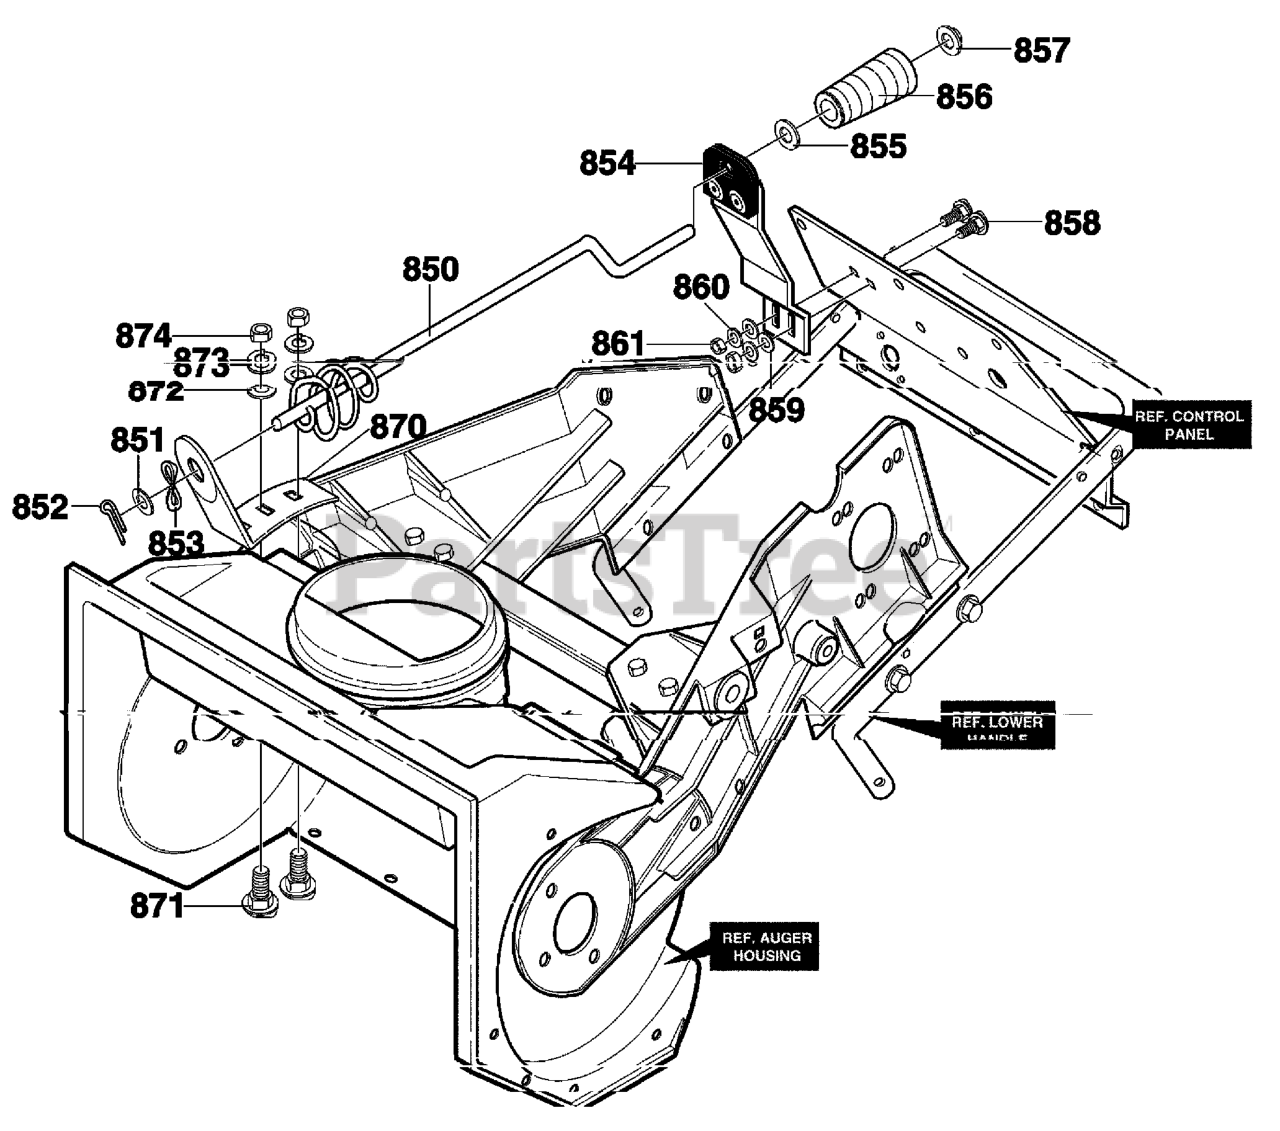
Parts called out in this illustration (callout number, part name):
850	ROD, CHUTE
851	WASHER, FLAT .406X.81X.066
852	PIN, COTTER
853	WASHER CURVED
854	ASSY, CHUTE CRANK
855	WASHER, FLAT .406X.81X.066
856	KNOB, SLEEVE
857	NUT, PUSH
858	BOLT,1/4-20X.63 CARR.
859	WASHER, FLAT .344X.69X.065
860	WASHER, .31X.58X.08
861	NUT, 1/4-20 REGHEX
870	BRKT, CHUTE ROTATE
871	BOLT, 5/16-18X.75 CARR
872	WASHER, FLAT .349X.69X.066
873	WASHER, SPTLK .31X.58X.08
874	NUT, 5/16-18 REGHEX
